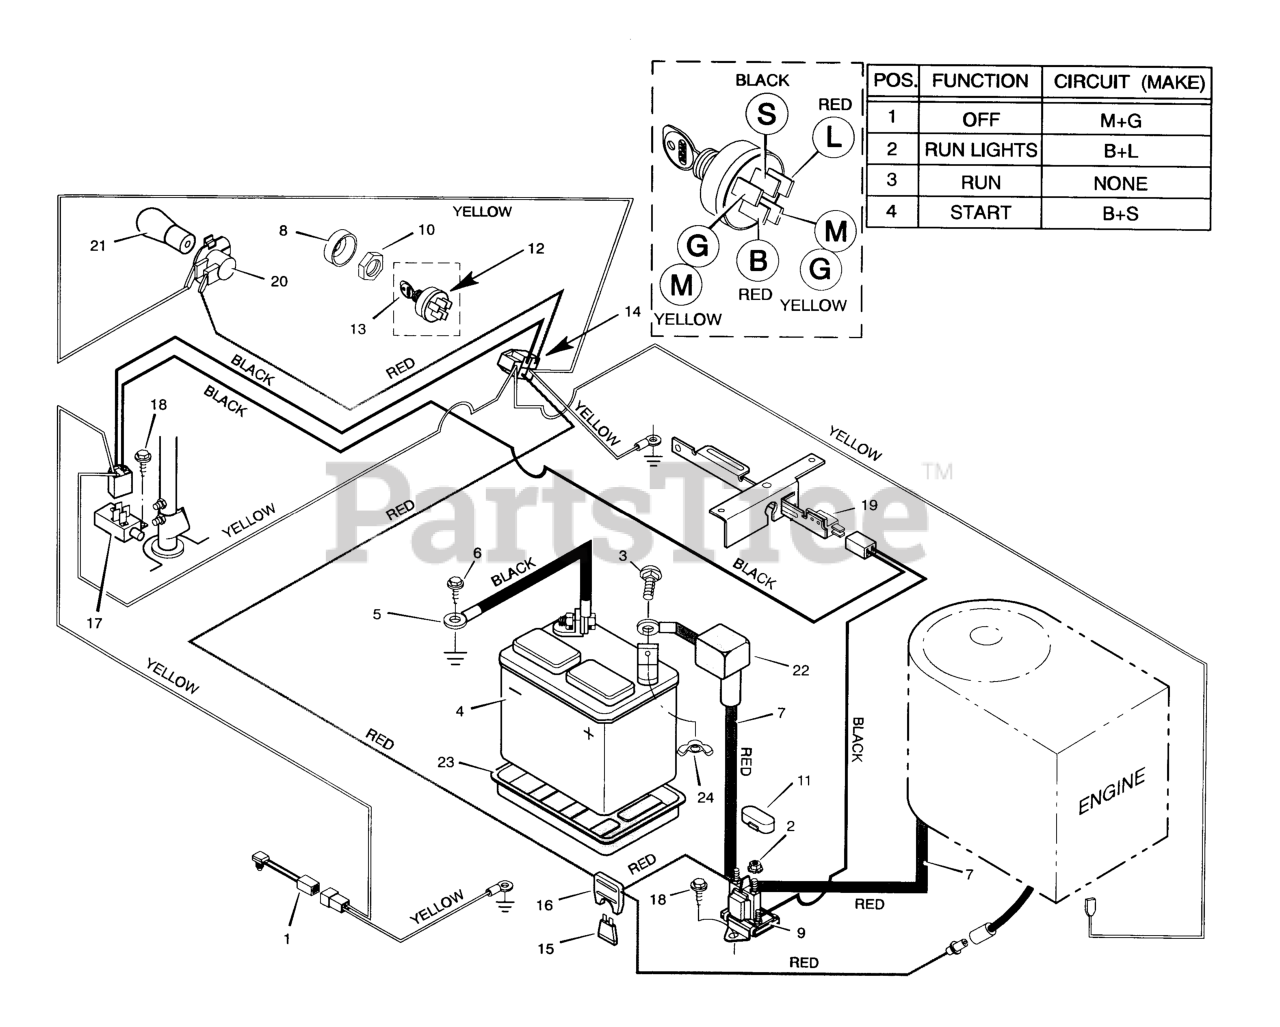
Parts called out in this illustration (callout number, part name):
1	Switch, Seat Sensor
2	Locknut
3	Bolt
4	Battery
5	Cable, Battery Ground
7	Cable, Red Battery
8	Cap, Ignition
9	Solenoid
10	Nut, Hex
11	Cover, Solenoid
12	Switch, Ignition
13	Key, Ignition
14	Harness, Chassis Wire
16	Holder, Fuse
17	Switch, Limit
19	Switch, Limit
20	Socket, Light
21	Bulb, Light
22	Cover, Terminal
23	Tray, Battery
24	Wingnut
